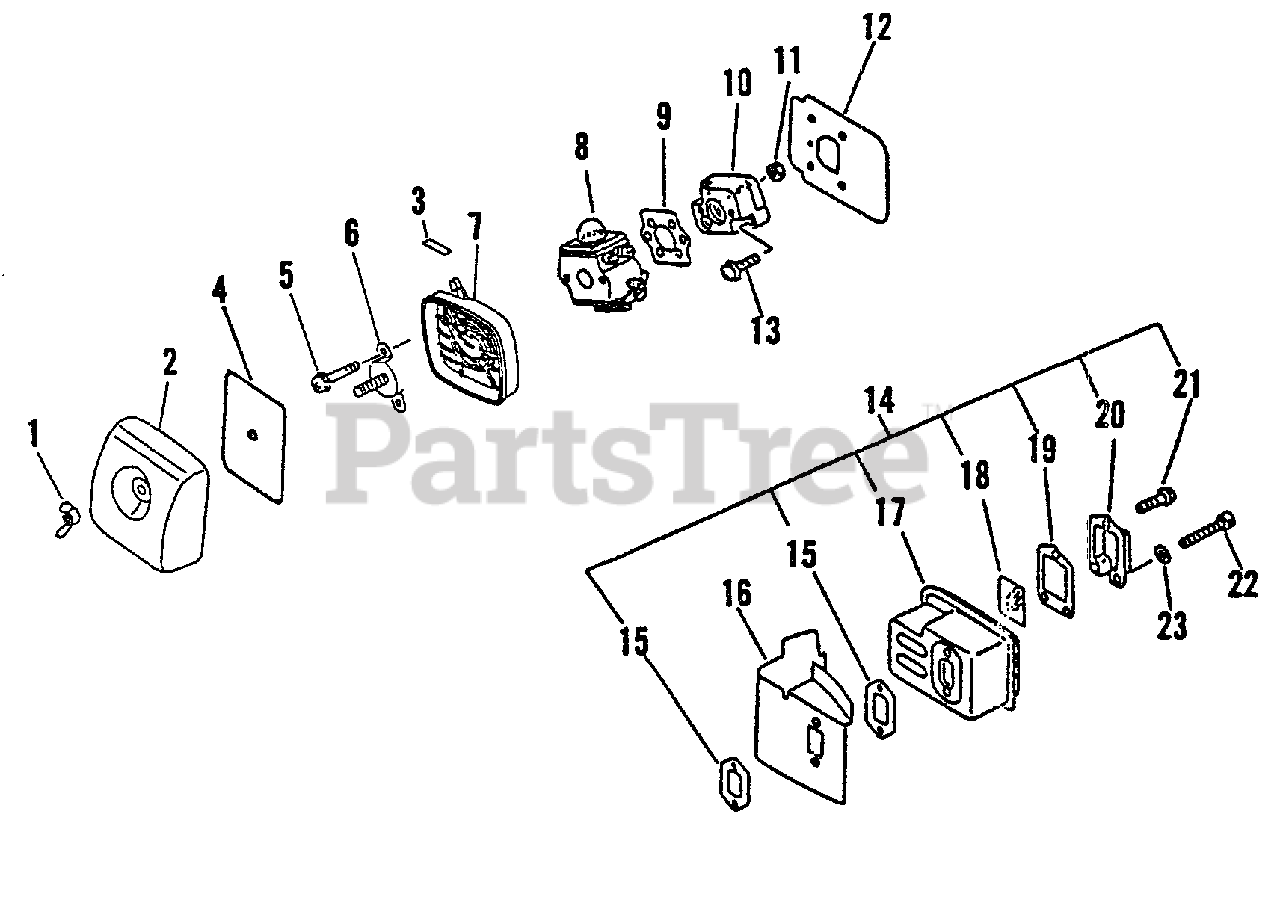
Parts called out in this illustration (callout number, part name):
1	WINGNUT - 6
2	COVER, AIR FILTER - BLACK
3	LABEL - CHOKE
4	FILTER, AIR
5	SCREW - 5X65
6	PLATE, PREVENT
7	AIR FILTER CASE ASSY
8	CARBURETOR C1U-K27B
9	GASKET, INTAKE
10	INSULATOR, INTAKE
12	SHIELD, INTAKE
13	SCREW - 5X20
14	MUFFLER ASSY
15	GASKET, EXHAUST
16	SHIELD, EXHAUST
18	SCREEN, SPARK ARRESTOR
19	GASKET, EXHAUST
20	GUIDE, EXHAUST - OUTER
21	SCREW - 4X10
22	SCREW - 5X50
23	WASHER - 5
